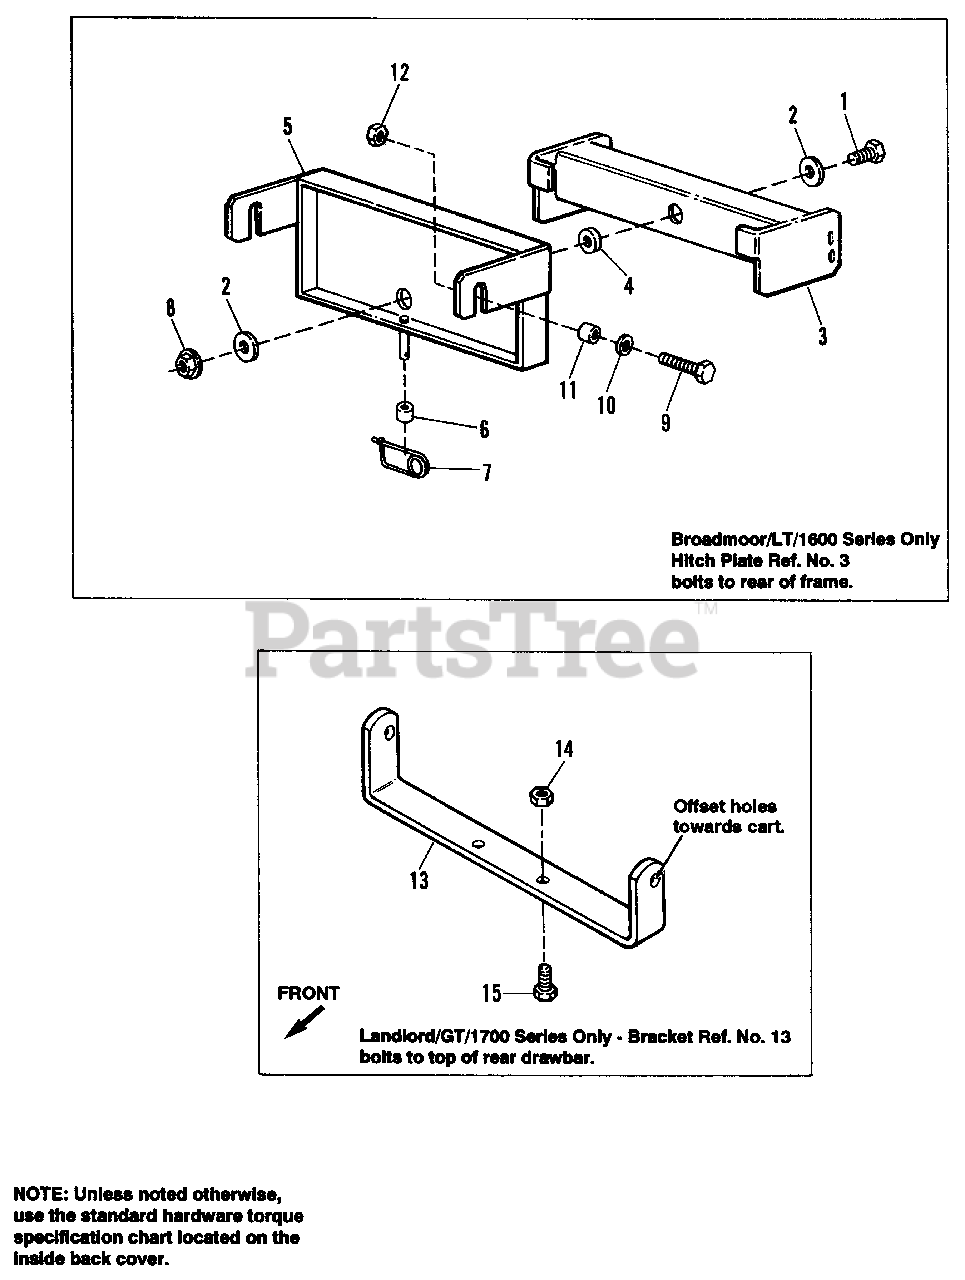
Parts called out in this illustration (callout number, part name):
2	WASHER, Plain, 1/2
3	PIVOT, Plate, Hitch
5	SUPPORT, Plate, Hitch
7	PIN, Safety
8	LOCKNUT, Hex, Flange, 1/2-13
9	CAPSCREW, 3/8-16 x 1-1/4
10	WASHER, Plain, 3/8
12	NUT, Hex, Lock, 3/8-16
13	BRACKET, "U" Witch
14	NUT, Hex, Lock Esna, 1/2-13
15	CAPSCREW, Hex, 1/2-13 x 1-1/2
